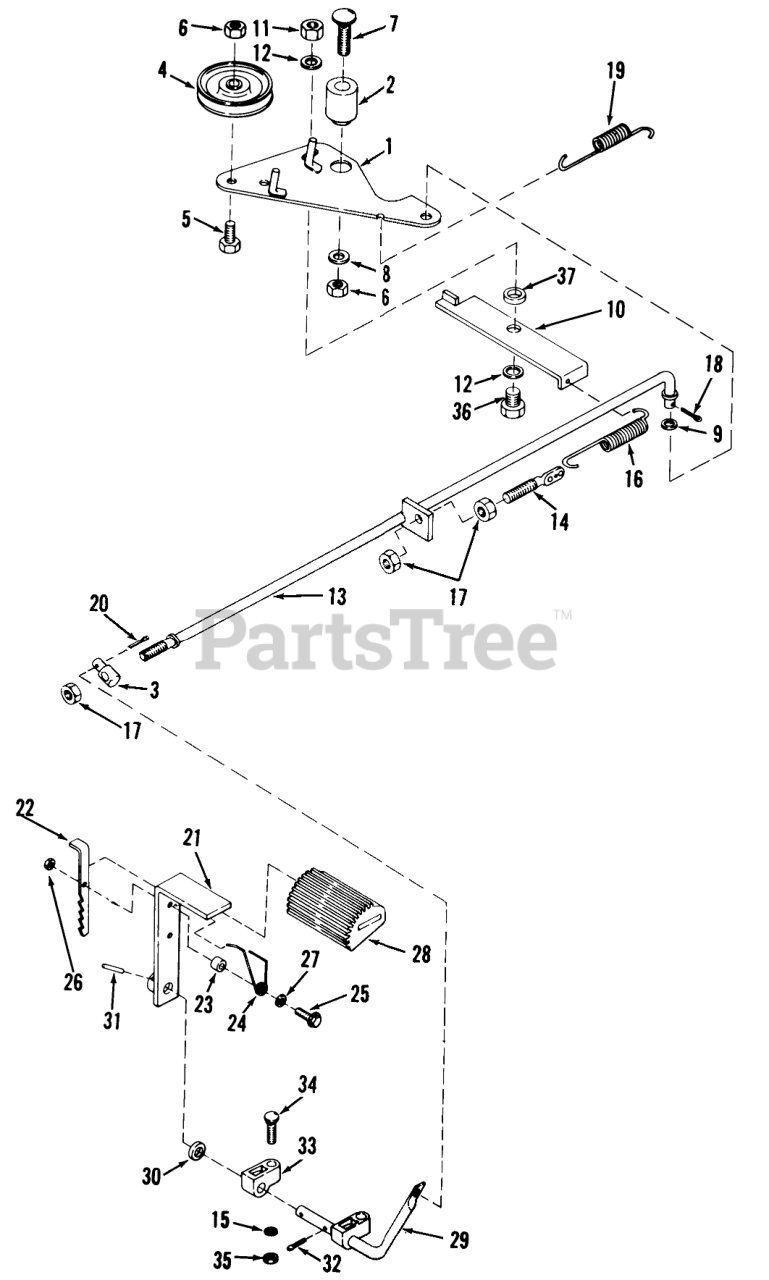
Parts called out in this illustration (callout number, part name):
3	TRUNNION-LIFT
4	PULLEY-IDLER STATION
8	WASHER
12	WASHER 5/16 SAE
19	SPRING
27	WASHER
28	Pad, Brake Pedal
31	Roll Pin
